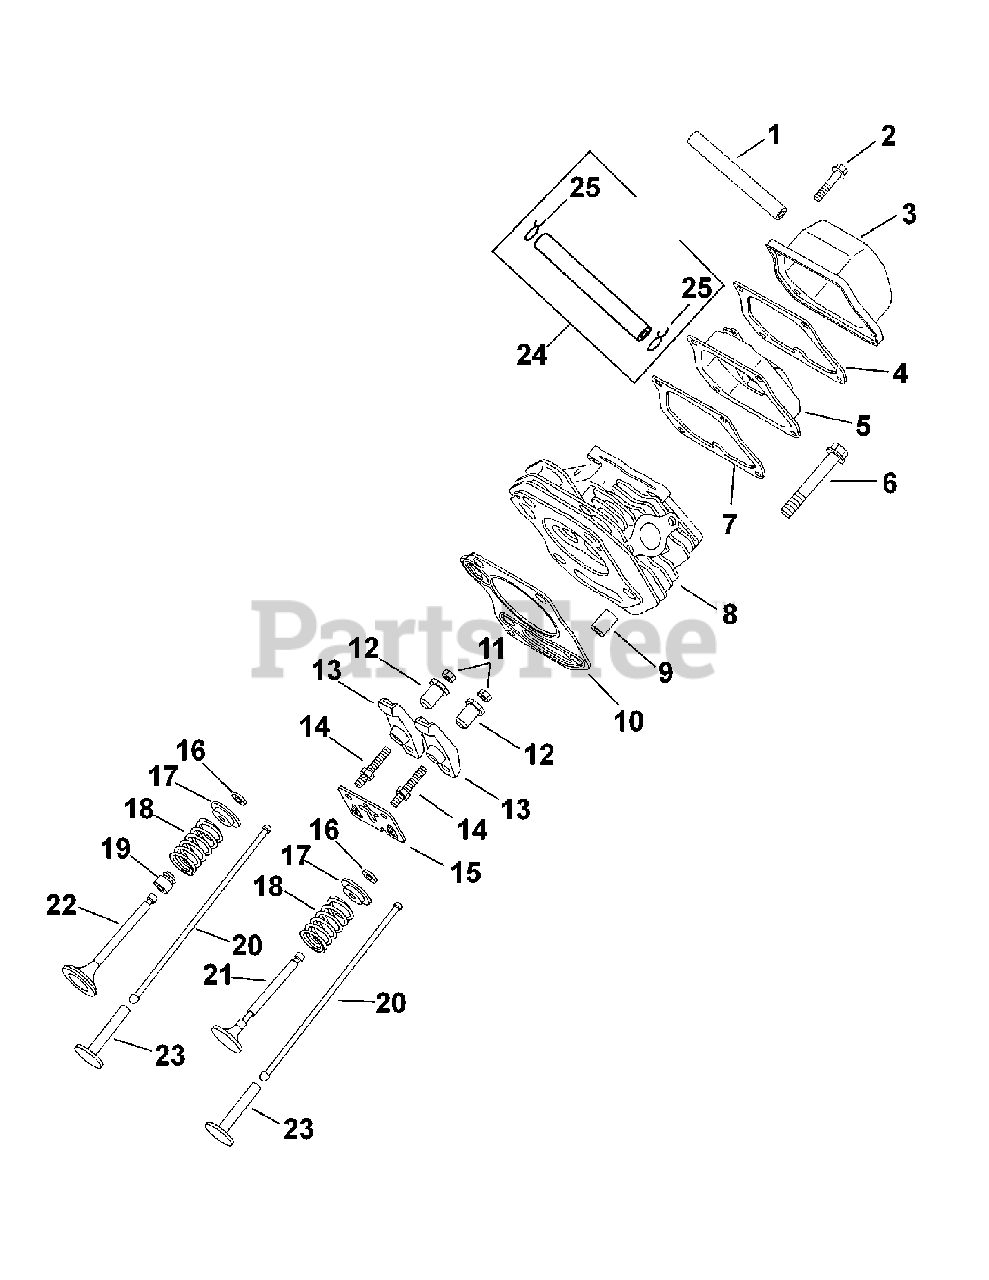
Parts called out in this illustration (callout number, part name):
1	Hose, Breather
4	Gasket, Valve Cover
5	Breather Assembly
6	Screw, Cyl Head
7	Gasket, Breather
8	Cylinder Head
10	Gasket, Cyl Head
12	Pivot, Rocker Arm
14	Screw, Valve Adj
16	Valve, Cotter
17	Cap, Valve Spring
18	Spring, Valve
19	Seal, Valve Stem
21	Valve, Exhaust
22	Valve, Intake
23	Lifter,-Valve
